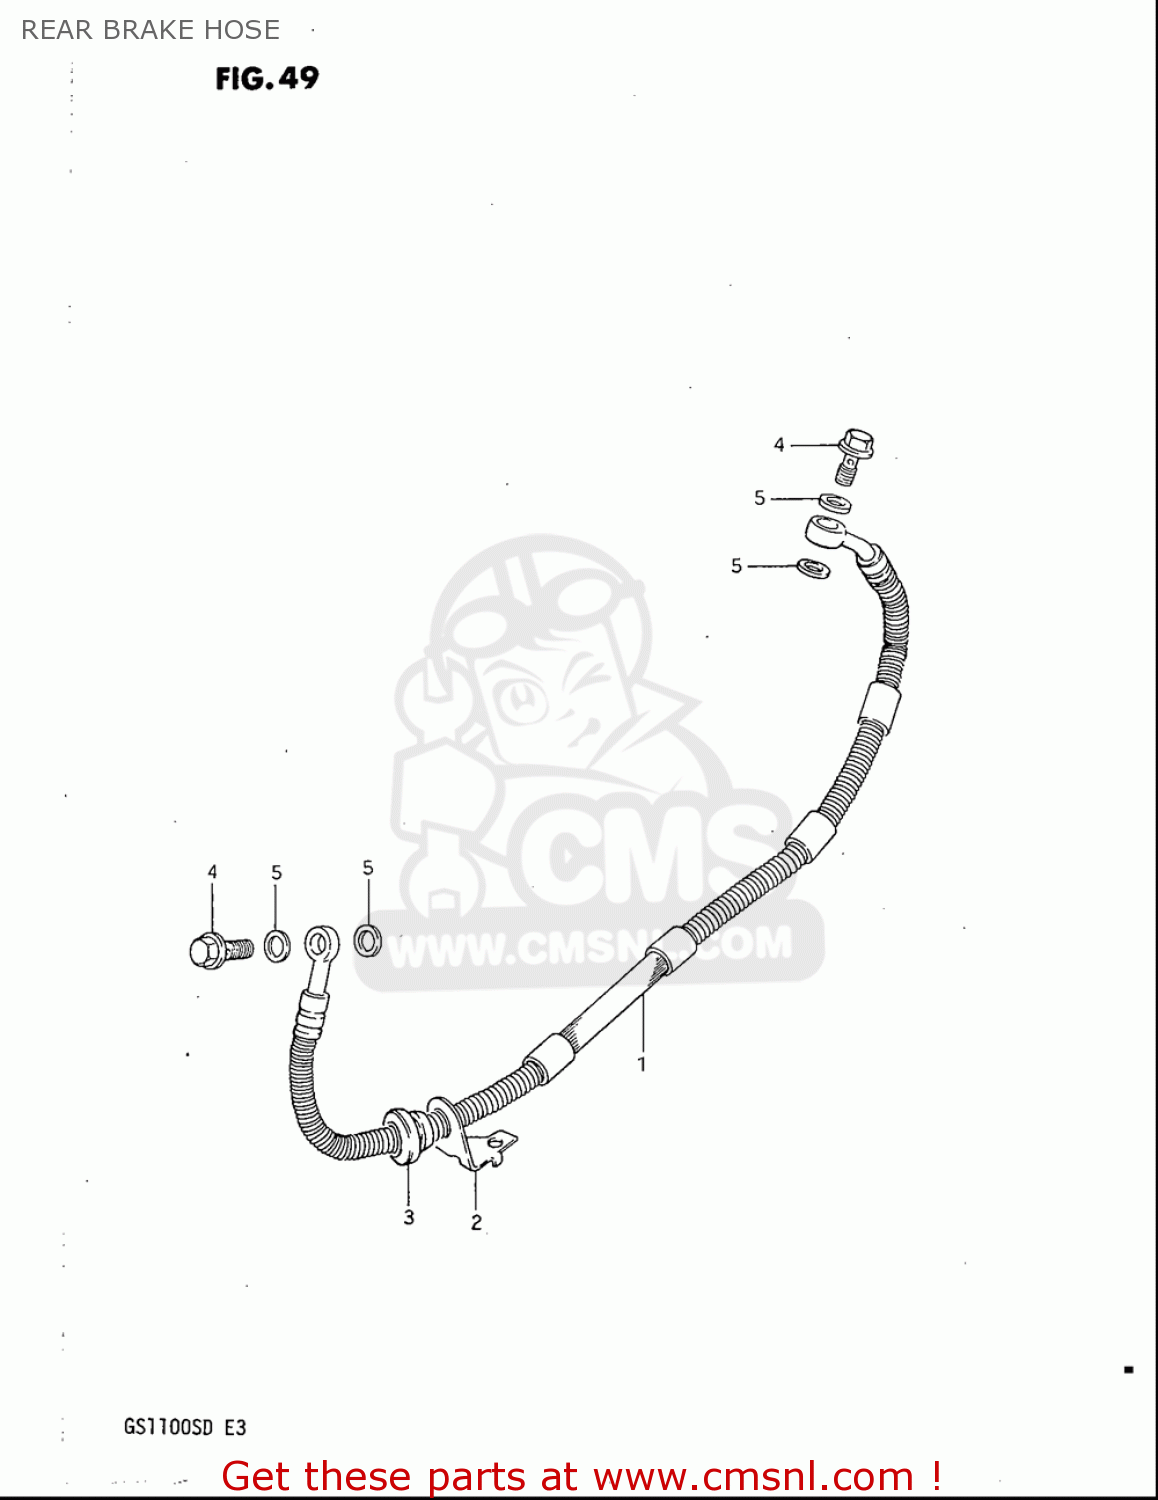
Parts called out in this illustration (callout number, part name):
1	HOSE,FR BRAKE NO.1
2	GUIDE,BRAKE HOSE
3	GROMMET,BRAKE HOSE GUIDE
4	BOLT UNION
5	WASHER(10X15X1.5)
